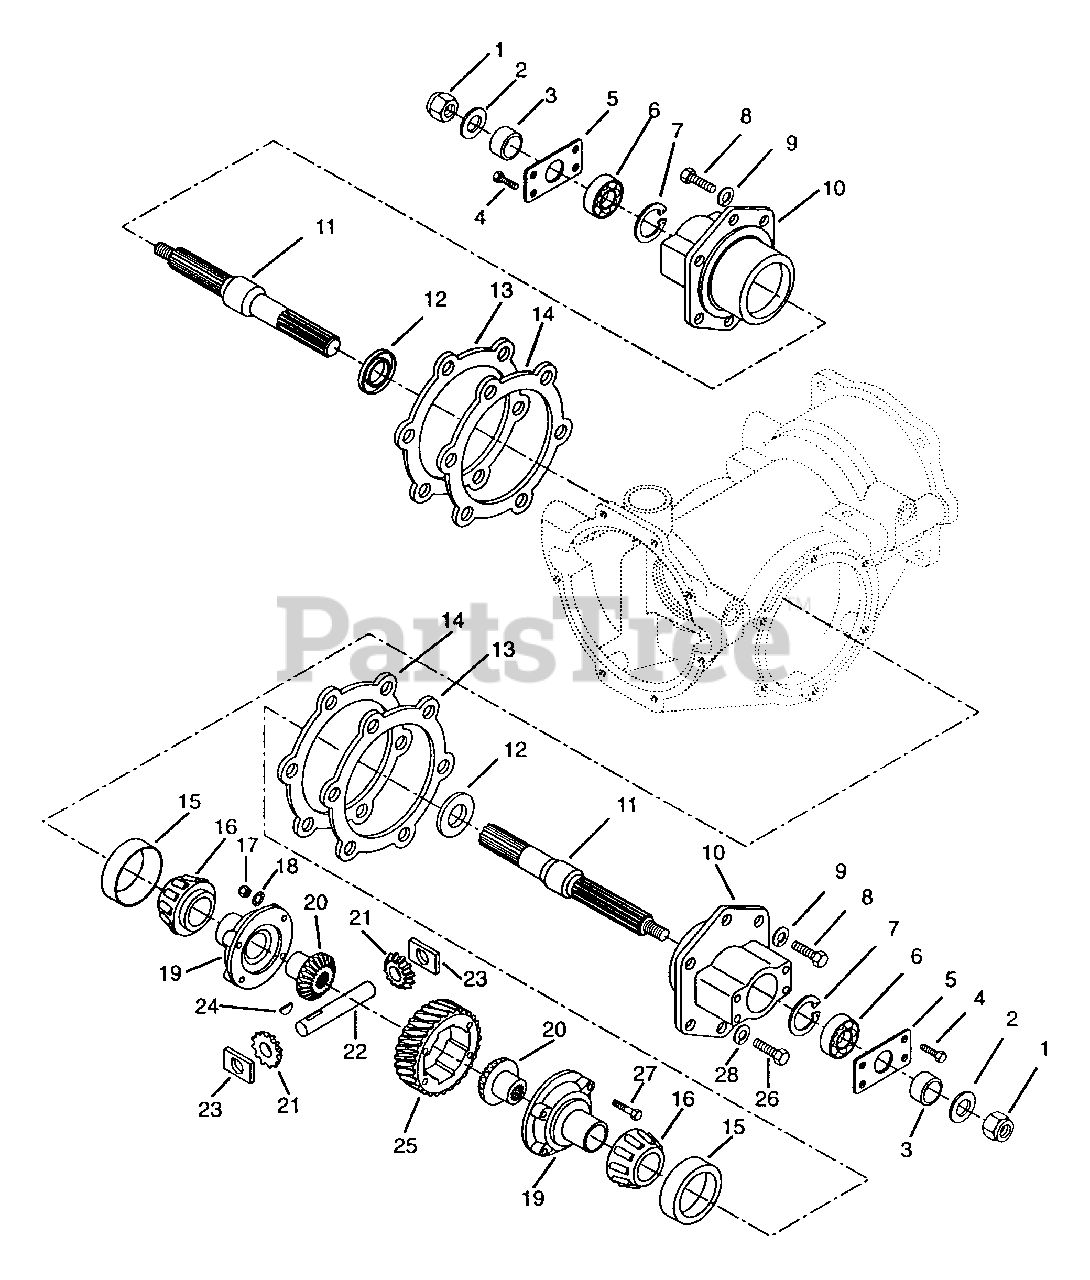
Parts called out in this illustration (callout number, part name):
1	Nut-Locking-Jam-Nylon .75-10
2	Washer-Flat .812 x 1.469 x .134
3	Spacer 1.008 x 1.377 x .509
4	Bolt-Hex .38-16 x .75 Grade 5
5	Plate, End
6	Bearing-Ball 1.0 x 2.0 x .56
7	Ring-Retaining-Internal 2.210 x .062
8	Bolt-Hex .50-13 x 1 Grade 5
9	Washer-Lock .50 Reg.
10	Housing, Axle
11	Axle, Straight
12	Seal 1.188 x 2.000 x .250
13	Shim, Axle Housing .005
14	Gasket, Axle Housing
15	Cup, Roller Bearing 82 MM x 17 MM
16	Cone, Roller Bearing 50 MM x 21.5 MM
17	Nut-Hex .312-24 Grade 2
18	Washer-Lock Internal .313 x .030
19	Housing, Differential
20	Gear, Differential Bevel
21	Gear, Spider Bevel
22	Pin, Spider Pinion
23	Block, Drive
24	Key-Woodruff .13 x .38
25	Gear, 6-Lead Worm
26	Bolt-Hex .50-13 x 1.312 Grade 5
27	Bolt-Hex .31-24 x 2.75
28	Seal-Oil Drain .563 x 1.250 x .091
